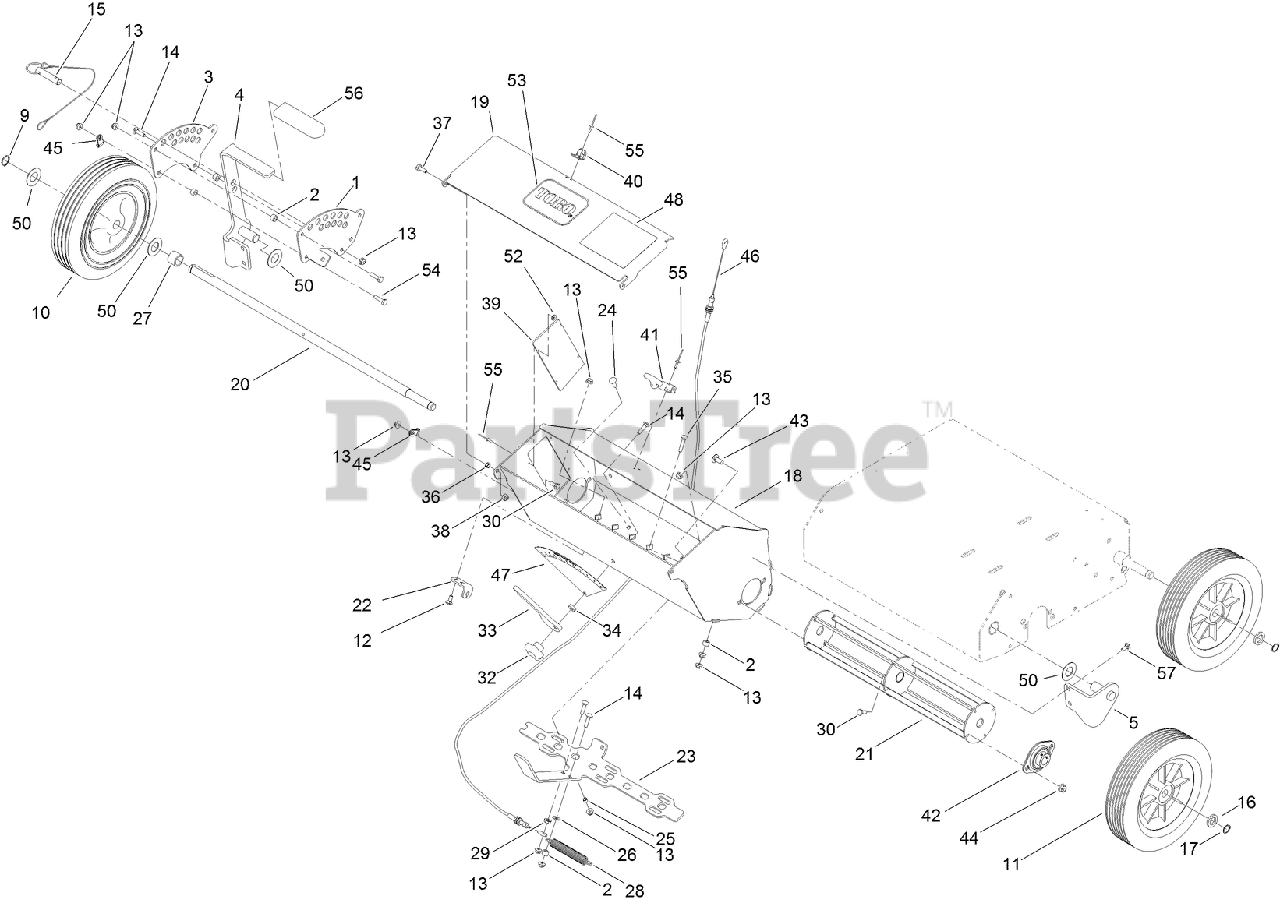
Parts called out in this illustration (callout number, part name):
1	BRACKET
2	SPACER
4	BRACKET-ADJUST, HEIGHT
5	BRACKET-WHEEL
9	Ring-Snap
11	WHEEL-TRANSPORT 10"
12	SCREW-CARR
13	NUT-HF
14	SCREW-CARR
15	PIN-HITCH
16	SPACER-BEARING
17	RING-SNAP, EXTERNAL
18	BOX-SEEDER
19	COVER-SEEDBOX
20	SHAFT-AGITATOR
22	BRACKET-SEED FLOW
23	GATE-SEED
24	BOLT-CARR
25	SPACER
26	WASHER-FLAT
27	SPACER-LOCKUP
28	SPRING-EXTENSION
29	NUT-HF
30	SCREW-HH
32	KNOB-HANDLE
33	GAUGE-SEED FLOW
34	SPACER
35	SCREW-CARR
36	BUSHING-FLANGE, SPLIT
37	SCREW-HH
38	NUT-LOCK, NI
39	WINDOW-SEEDER BOX
40	KEEPER-LATCH, RUBBER
41	LATCH-RUBBER
42	BEARING
43	SCREW-CARR
44	NUT-HF, NI
45	CLAMP-R
46	CABLE-GATE, SEED
47	DECAL-RATE, FLOW
48	DECAL-SEED GRAPH
50	WASHER-FLAT
52	WASHER-BACK
53	DECAL
54	SCREW-HH
55	RIVET-POP
56	GRIP-LEVER
57	BOLT-CARR
